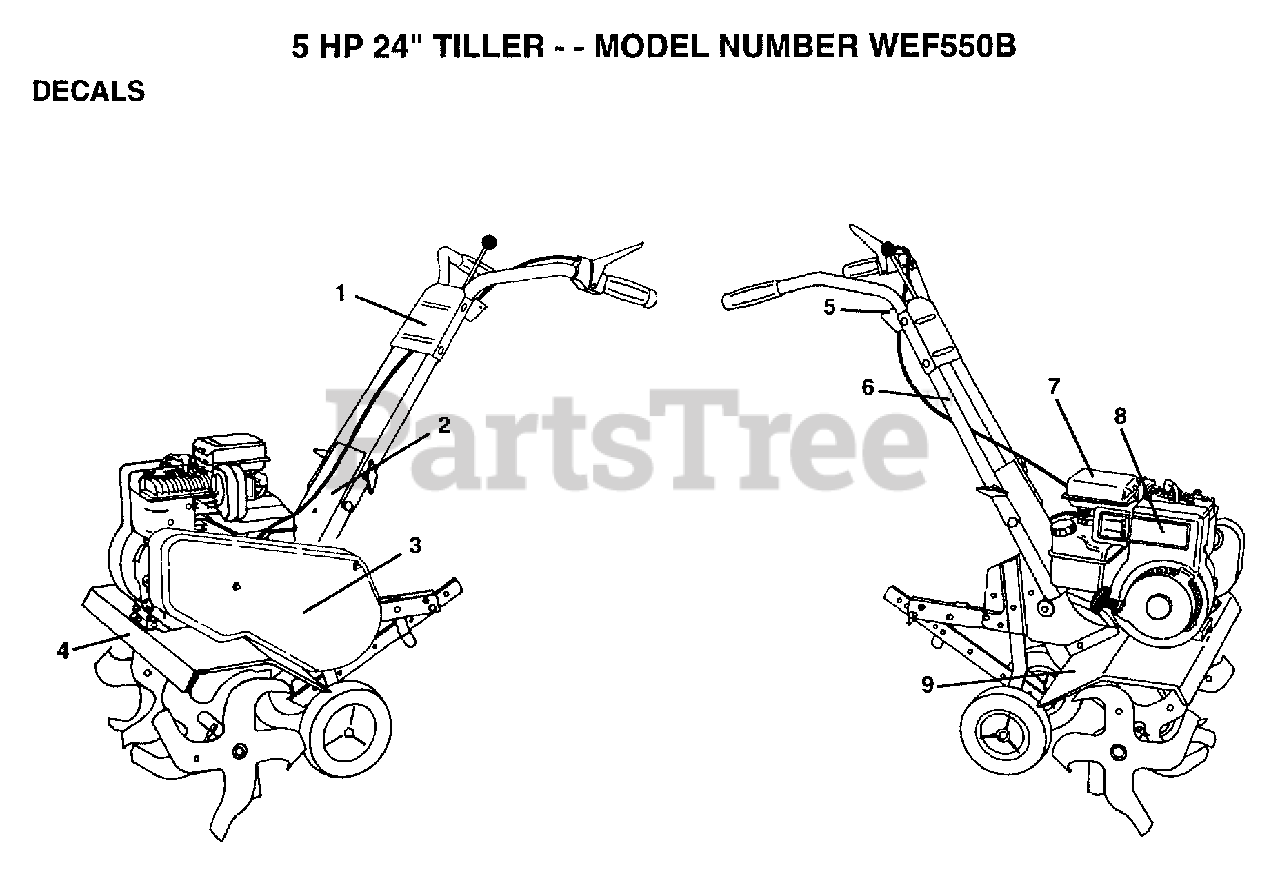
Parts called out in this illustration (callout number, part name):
2	DECAL.PNL.HANDLE
3	DECAL GUARD BELT
4	DECAL.SHIELD.TINE
5	DECAL REVERSE
6	DECAL TI
7	DECAL TI
